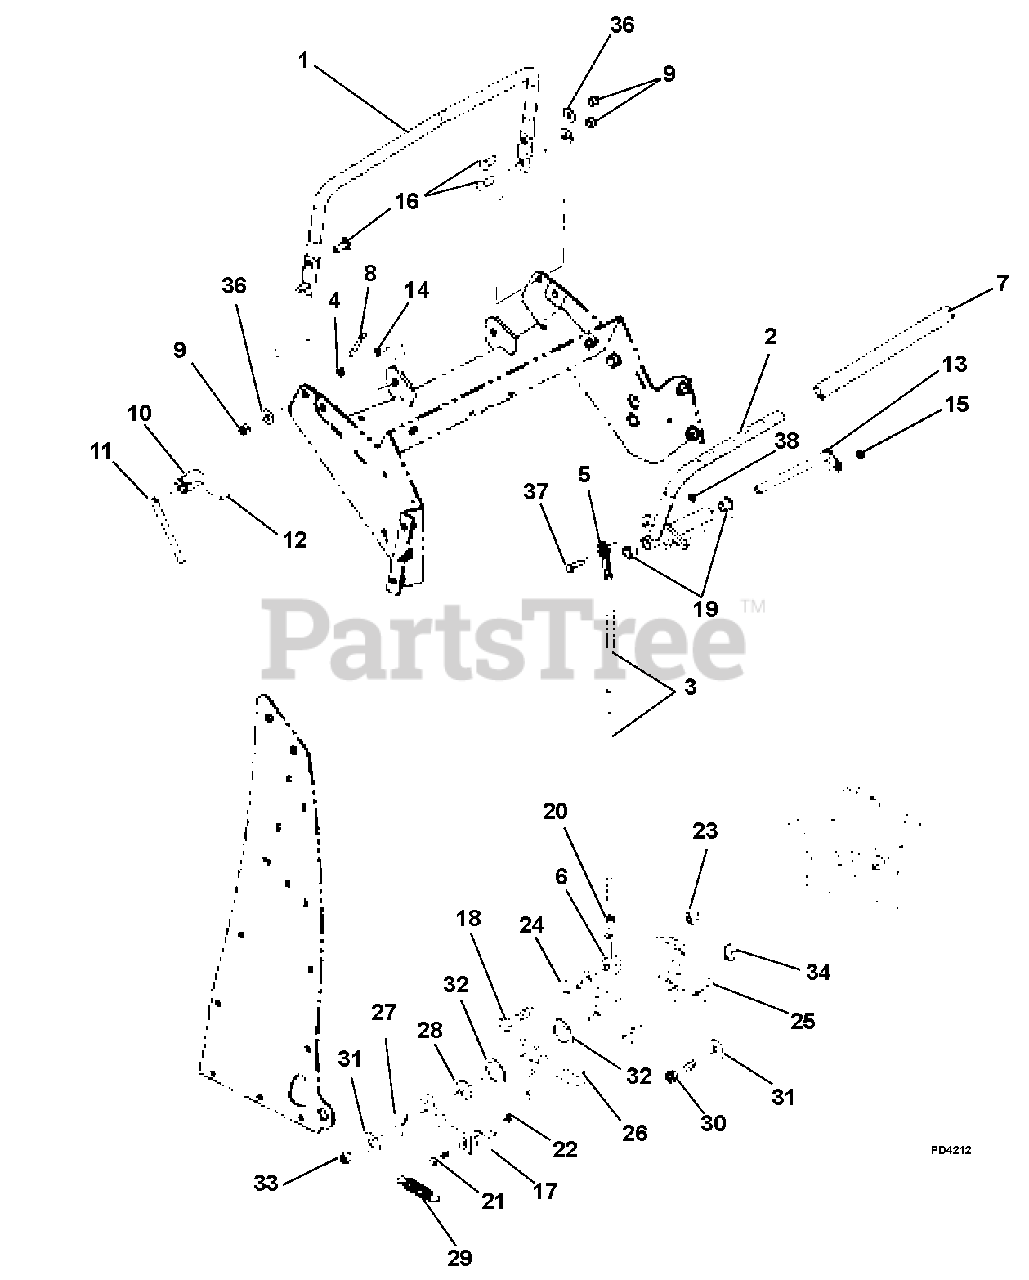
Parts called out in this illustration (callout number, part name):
1	Support, Handle
2	LH Control Lever w/ Grip
3	Control Rod
4	Flange Nut, M16 x 1.0
5	Alignaball, 5/16 LH Thread
6	Alignaball, 5/16 RH Thread
7	Grip, Control
8	Cap Screw, Reverse Stop M6 x 1
9	Nut, Lock, Nylon M10-1.5
10	Base, Lock Lever
11	Lever, Lock
12	Pin, Spring 5/32 x 1
13	Weldment, Pin and Lock
14	Bolt, Hex .25-20 x .75
15	Nut, Locking, Nylon .250-20
16	Bolt, Hex M10 x 1.5 x 25
17	Switch, Plunger (Double Pole) N.O.
18	Bolt, Hex .31-18 x 1.00
19	Bearing, Flange .500 x .620 x .500
20	Nut, Jam .31-24
21	Screw, Machine 10-24 x .625
22	Nut, Locking, Nylon 10-24 w/ Insert
23	Nut, Locking, Center .31-18
24	Arm, Control Return
25	Arm, Return
26	Arm, RH Inner Return
27	Arm, LH Outer Return
28	Spacer, Return
29	Spring, Extension
30	Screw, 5/16 x 1 Patch Lock
31	Washer
32	Washer, Nylon
33	Nut, Center Lock .31-24
35	Washer, Flat, Steel .406 x .812 x .065
36	Washer, Flat, Steel .438 x 1.00 x .083
37	Bolt, Hex .25-20 x .75
38	Nut, Locking, Nylon .312-18
